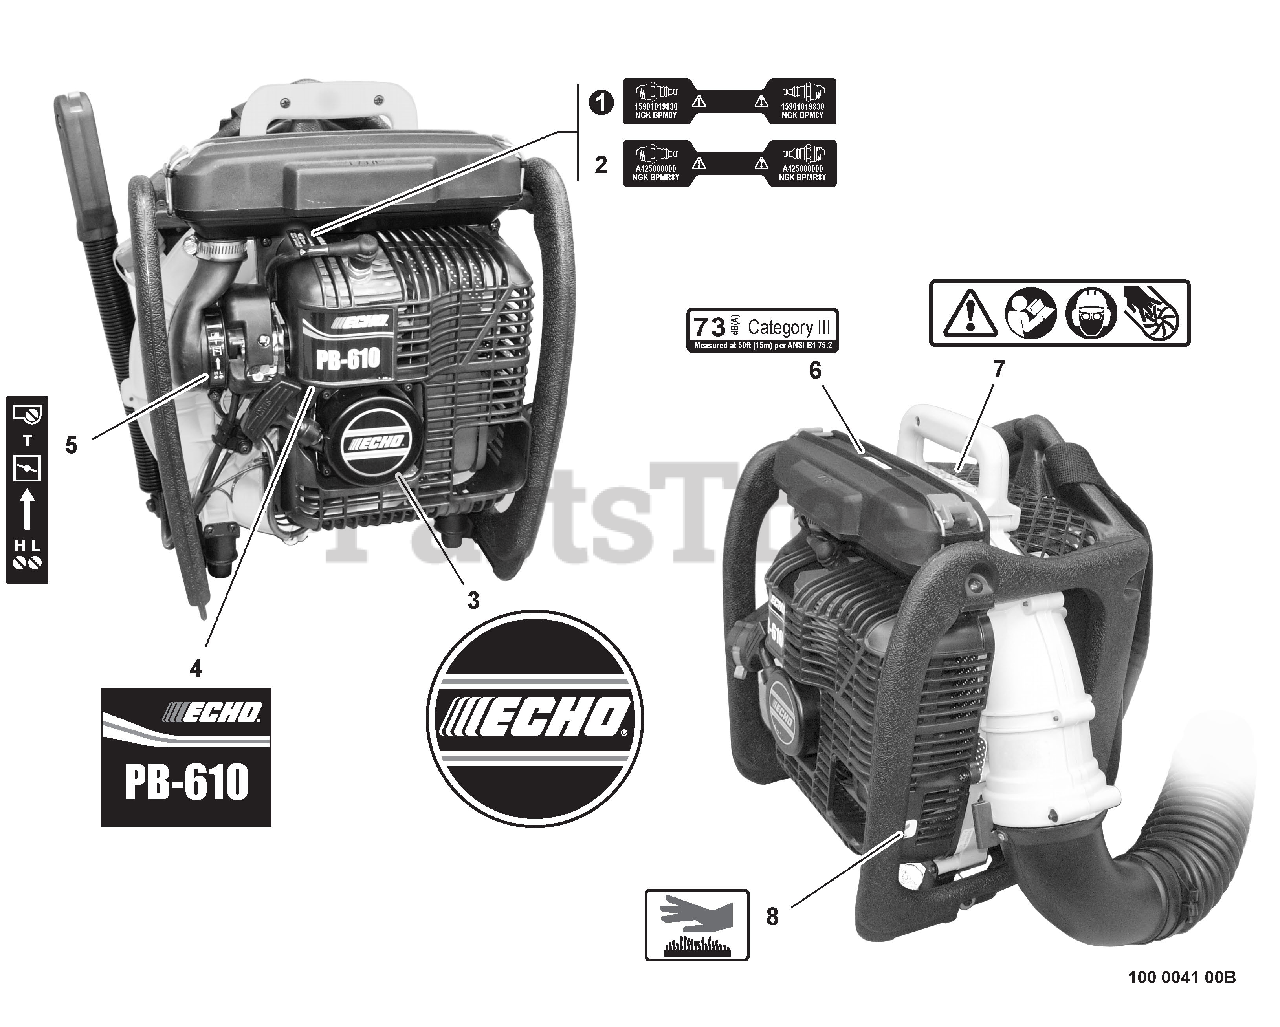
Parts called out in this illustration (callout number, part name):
1	LABEL - SPARK PLUG -- BPM-8Y
2	LABEL - SPARK PLUG -- BPMR-8Y
3	LABEL - ECHO
4	LABEL - MODEL PB-610
5	LABEL - CHOKE
6	LABEL - NOISE 73dB(A) CAT III
7	LABEL - CAUTION
8	LABEL - HOT SURFACE
